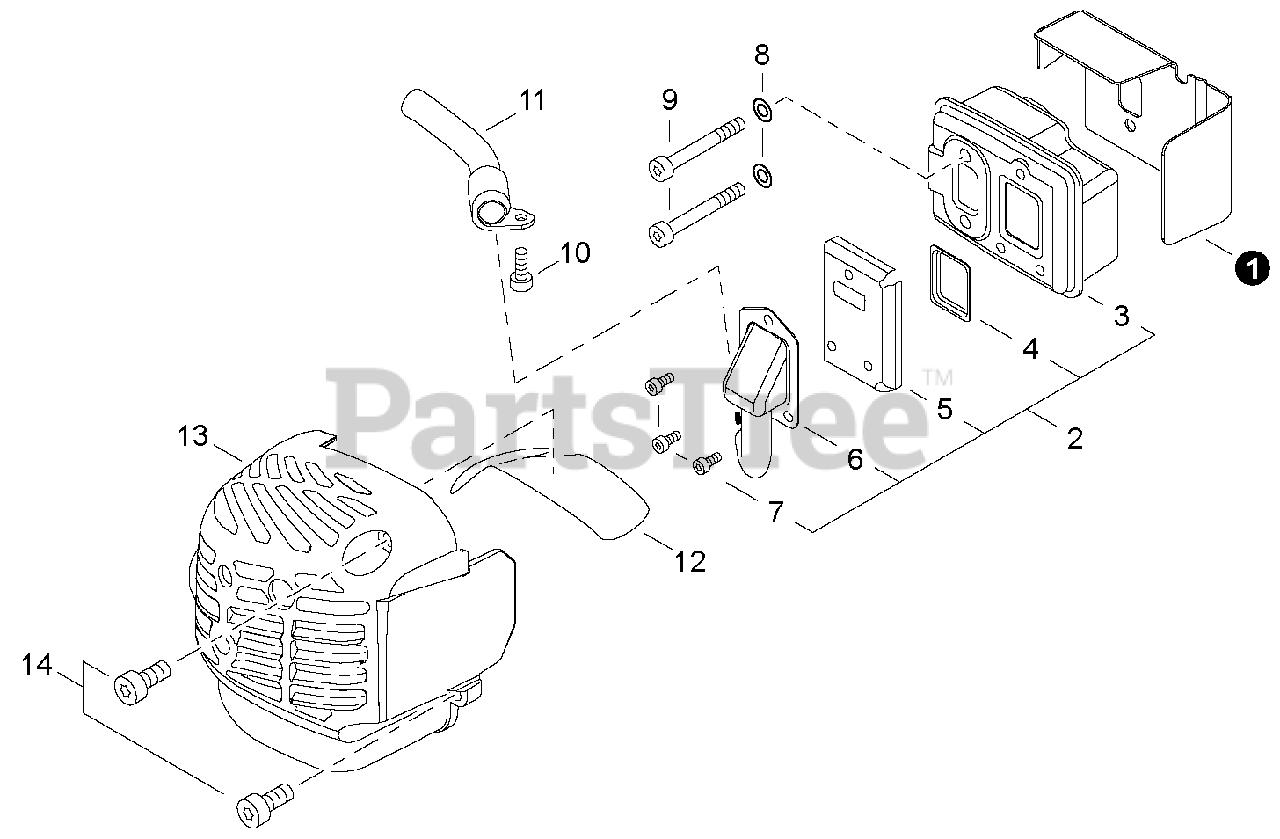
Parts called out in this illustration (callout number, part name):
1	SHIELD, EXHAUST
2	MUFFLER ASSY
3	MUFFLER
4	SCREEN, SPARK ARRESTOR
5	GASKET, EXHAUST
6	GUIDE, EXHAUST
7	SCREW - 4X8
8	WASHER - 5
9	SCREW - 5X55
10	SCREW - 5X10
11	GUIDE, EXHAUST
12	PLATE, INSULATOR
13	COVER, MUFFLER
14	SCREW - 5X16
